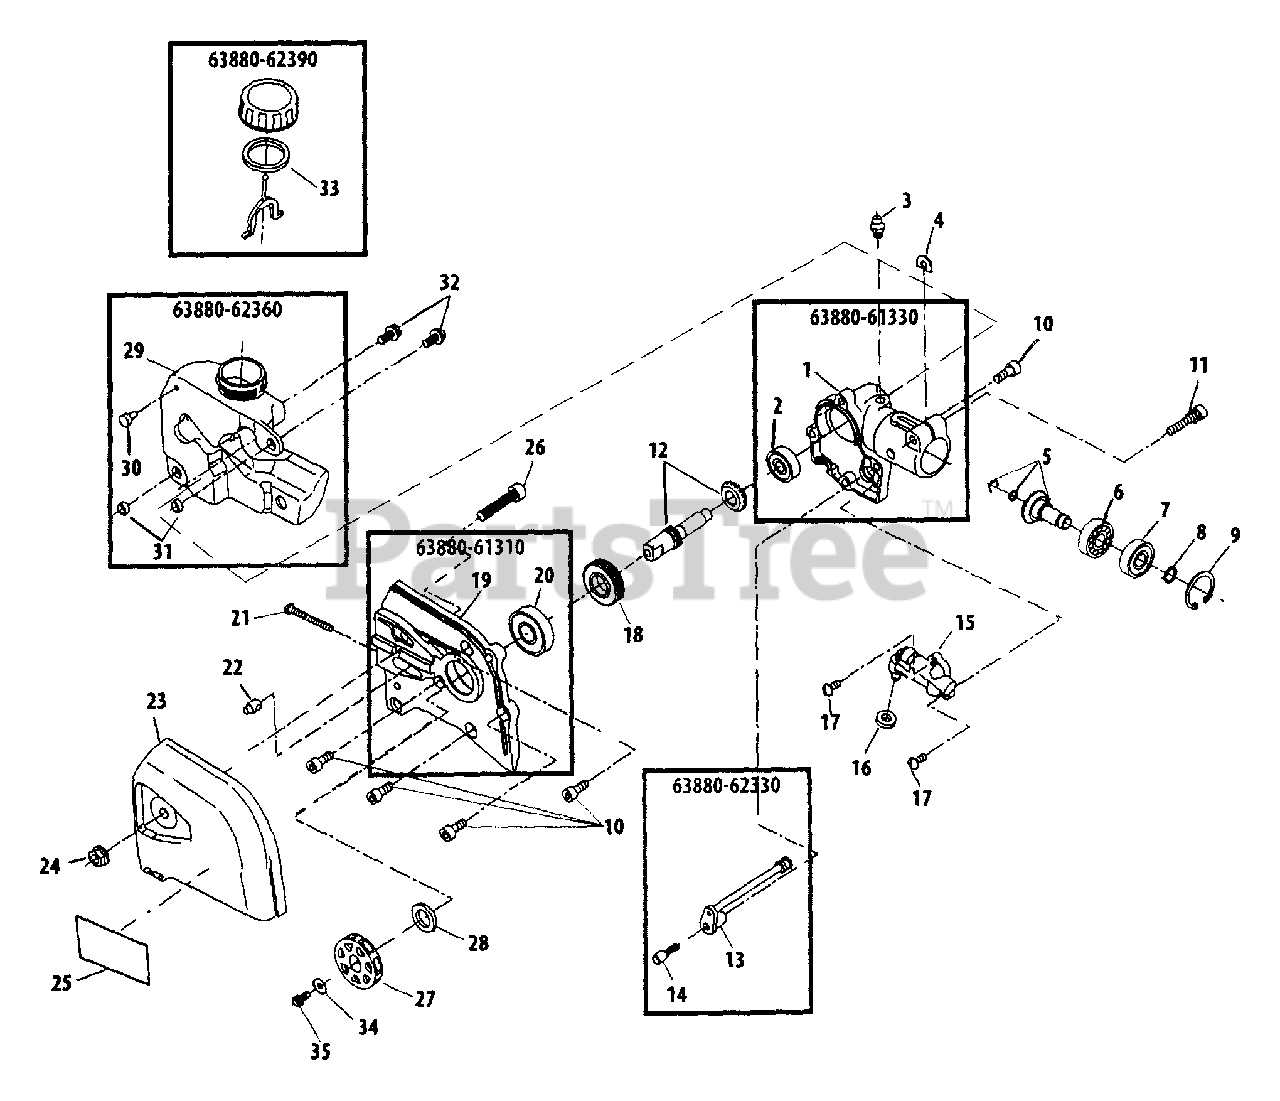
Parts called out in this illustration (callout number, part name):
1	CASE, GEAR - RIGHT
2	BEARING, BALL - 627ZZ
3	FITTING, GREASE
4	SHIM
5	GEAR - BEVEL
6	BEARING, BALL - 609
7	BEARING, BALL - 609ZZ
8	RING, RETAINING
9	RING, RETAINING - 24
10	SCREW - 5X12
11	SCREW - 5X25
12	GEAR - SHAFT
13	PIPE - OIL
14	FILTER
15	AUTO-OILER ASSY
16	GASKET, PUMP
17	SCREW - 4X10
18	GEAR - WORM
19	GEAR CASE ASSY - LEFT
20	BEARING, BALL - 6001DDU
21	SCREW - 4X35
22	TENSIONER, CHAIN
23	COVER
24	NUT - 6 -- FLANGE
25	LABEL - CAUTION
26	SCREW - 6X30
27	SPROCKET
28	COLLAR
29	TANK, OIL
30	VALVE, OIL
32	SCREW - 5X12
33	GASKET, CAP
34	WASHER - 6
35	SCREW - 6X14
63880-61310	GEAR CASE ASSY - LEFT
63880-61330	GEAR CASE ASSY - RIGHT
63880-62330	OIL TUBE ASSY
63880-62360	OIL TANK ASSY
63880-62390	OIL CAP ASSY
